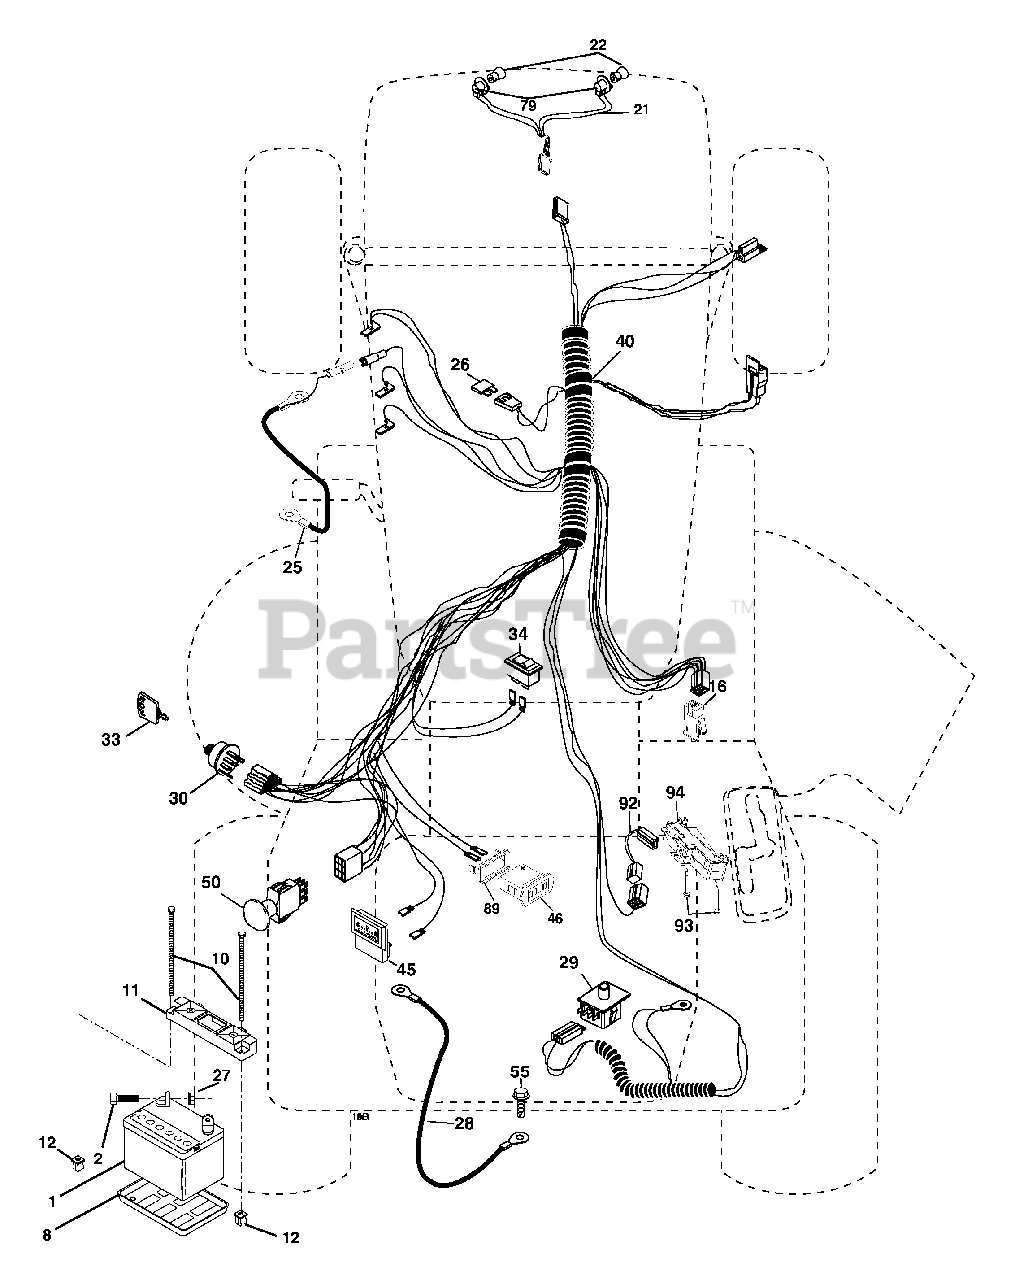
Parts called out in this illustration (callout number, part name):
1	Battery
2	Bolt Hex Hd 1/4-20 unc x 3/4
8	Tray, Battery
10	Bolt, BTR FRT 1/4-20 x 7.5
11	Hold Down Battery, Front
12	Nut, Push, Nylon
16	Switch Interlock Push-In
21	Harness Asm Light W/Bulbs
22	Bulb Light
25	Cable Battery
26	Fuse
27	Nut Keps Hex 1/4-20 unc
28	Cable Ground
29	Switch Seat
30	Switch Ign
33	Key Ign
34	Switch Light/Reset
40	Harness Ign.
42	Cover Terminal
45	Ammeter Rectangular
46	Hourmeter Snap-In
50	Switch, PTO
55	Screw Thdrol 5/16-18 x 1/2
79	Bulbholder
89	Bracket Snap-In Hourmeter
92	Harness Pigtail Reverse Switch
93	Screw Plastite 10-1/4 x 2.0
94	Module Reverse Switch
